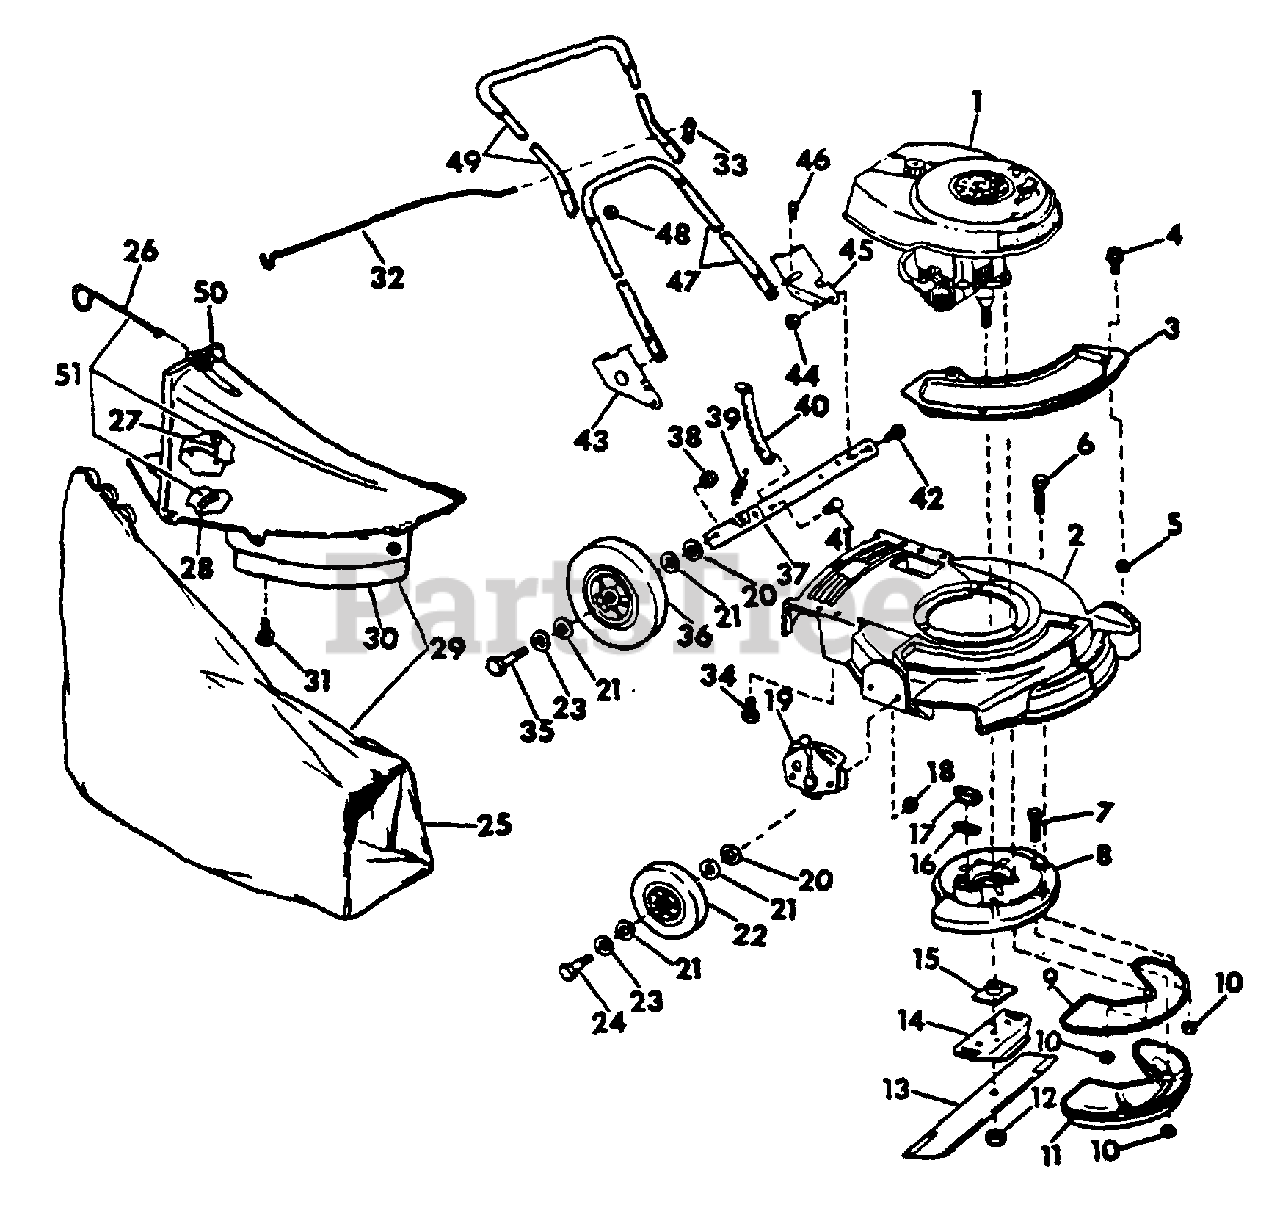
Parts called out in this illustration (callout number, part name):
1	ENGINE, IH
2	HOUSING & GROMMET ASSY. 19 IN.
3	COVER, CHUTE OPENING
4	SCREW, HEX-HD
5	NUT, GROMMET
6	SCREW, MUFFLER PLATE TO HSG
7	SCREW, MUFFLER TO MUFFLER PLATE
8	PLATE W/SCREW, MUFFLER
9	GASKET, MUFFLER
13	BLADE. 19 IN.
14	STIFFENER, BLADE
15	COLLAR & PLATE
16	GASKET, EXHAUST
17	SLEEVE, EXHAUST GASKET
18	NUT, HEIGHT ADJ MTG
19	ADJUSTMENT, HEIGHT
21	WASHER, FELT
22	WHEEL & TIRE, 6 IN.
23	WASHER, WHEEL BOLT HD
24	BOLT, WHEEL FRT SHOULDER
26	GUARD, WHEEL
29	CHUTE ASSY
30	SKIRT ASSY, CHUTE
32	ROD, GRASS BAR
34	SCREW, HANDLE BRACKET
35	BOLT, REAR WHEEL
36	WHEEL & TIRE, 8 IN.
38	NUT, REAR WHEEL BOLT
39	SPRING, HEIGHT ADJ
40	LEVER, HEIGHT ADJ REAR
43	BRACKET, HANDLE RH
44	NUT, WHEEL LEVER BOLT
45	BRACKET, HANDLE LH
47	HANDLE, BOTTOM
48	NUT, CENTERLOCK
49	HANDLE GRIP, TOP
51	GUARD ASSY, WHEEL
